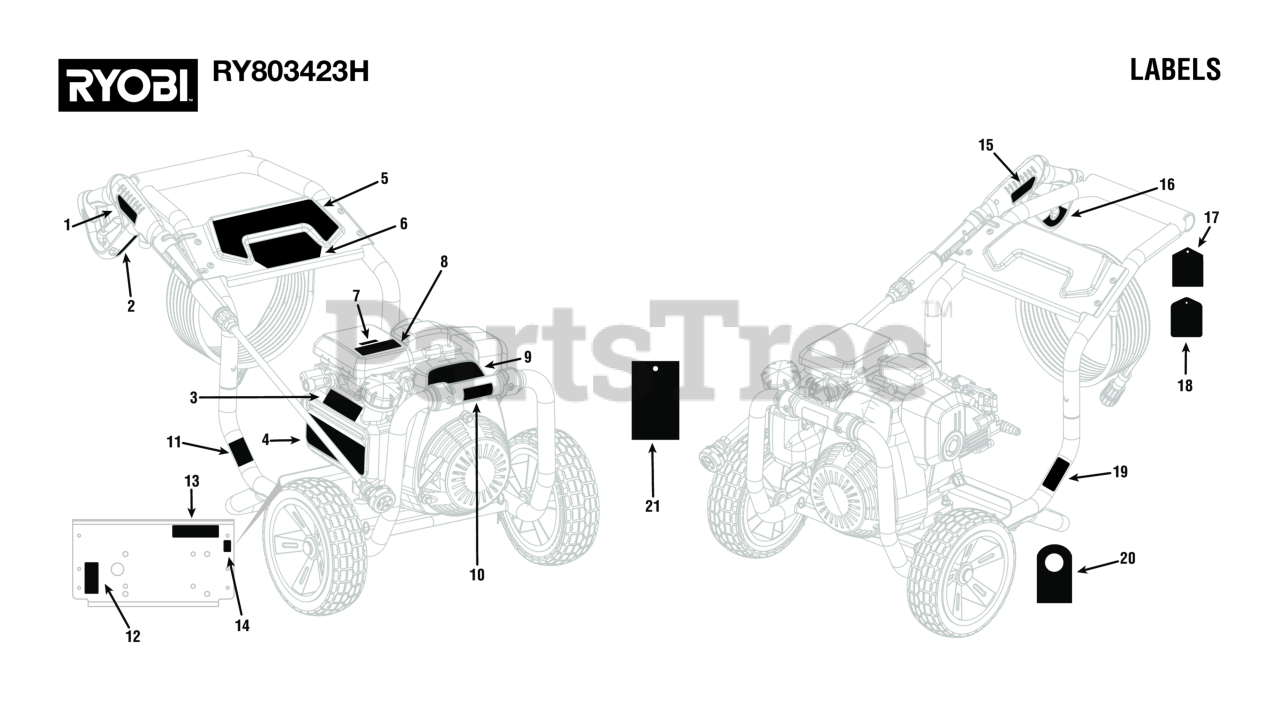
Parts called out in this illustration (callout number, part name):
1	LABEL, TRIGGER HANDLE LOGO
2	Trigger Handle Data Label
3	No E85 Label
4	Danger Label
5	Logo Label
6	Performance Label
7	EMC ICES-2/NMB-2 Label (Canada)
8	Hot Surface and
9	Engine Brand Label
10	40V Lithium Label (Right)
11	49 State Label
12	Warning Label
13	Combustion Warning Label
14	Oil Fill Location Label
15	Trigger Handle Warning Label (English)
16	Label (Trigger Handle Warning, French & Spanish)
17	5- In- 1 Nozzle Hangtag
18	Quick Start Hangtag
19	Inquires Label (Ryobi)
20	Label (Oil Dipstick Hangtag)
21	Danger Hangtag
